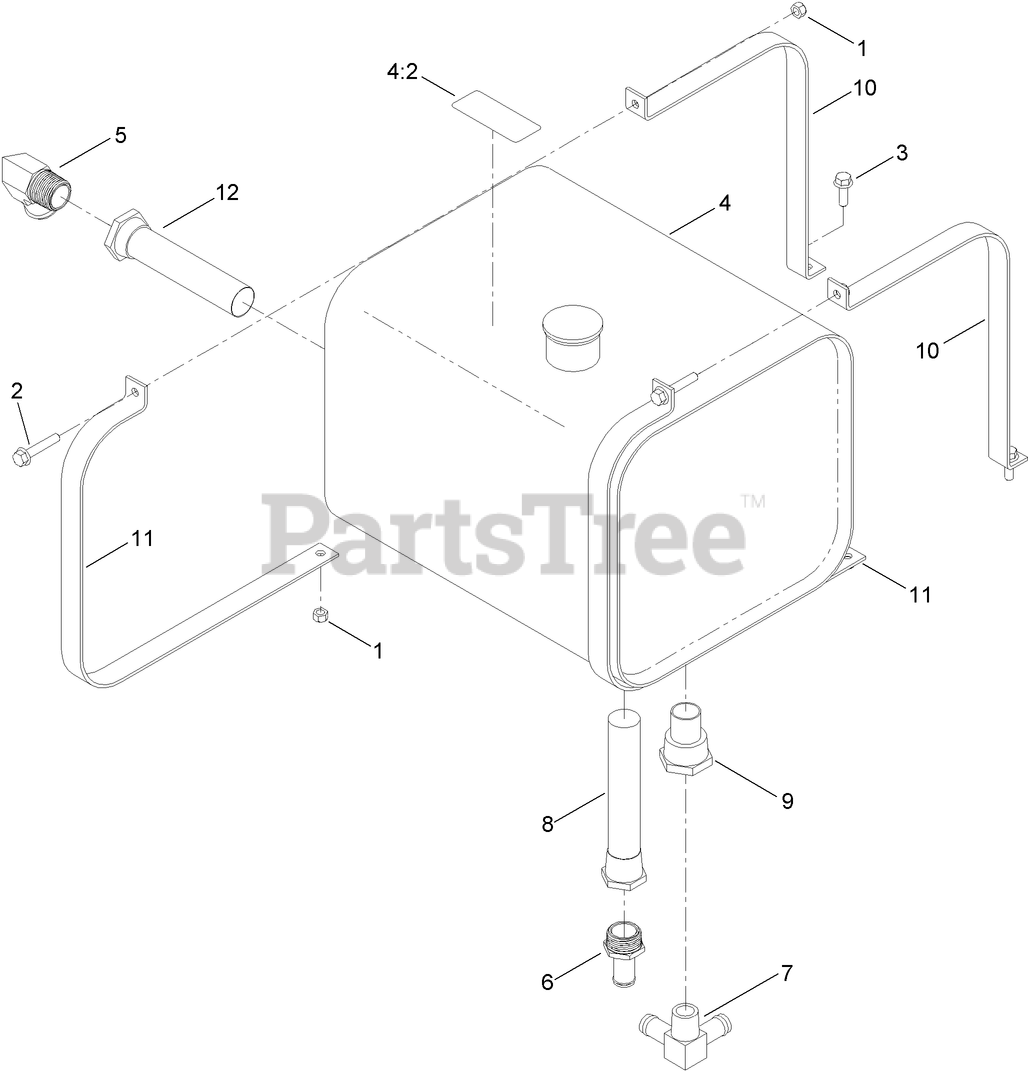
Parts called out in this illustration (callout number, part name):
1	NUT-LOCK, NI
2	SCREW-HHF
3	SCREW-HHF
4	HYD TANK ASM
4:2	DECAL-HYD FLUID
5	FITTING-ELBOW, 90
6	FITTING-STRAIGHT
7	FITTING-ELBOW, LATERAL
8	FILTER ASM
9	INDUCER-PRESSURE
10	STRAP-TANK
11	STRAP-TANK
12	FILTER ASM
